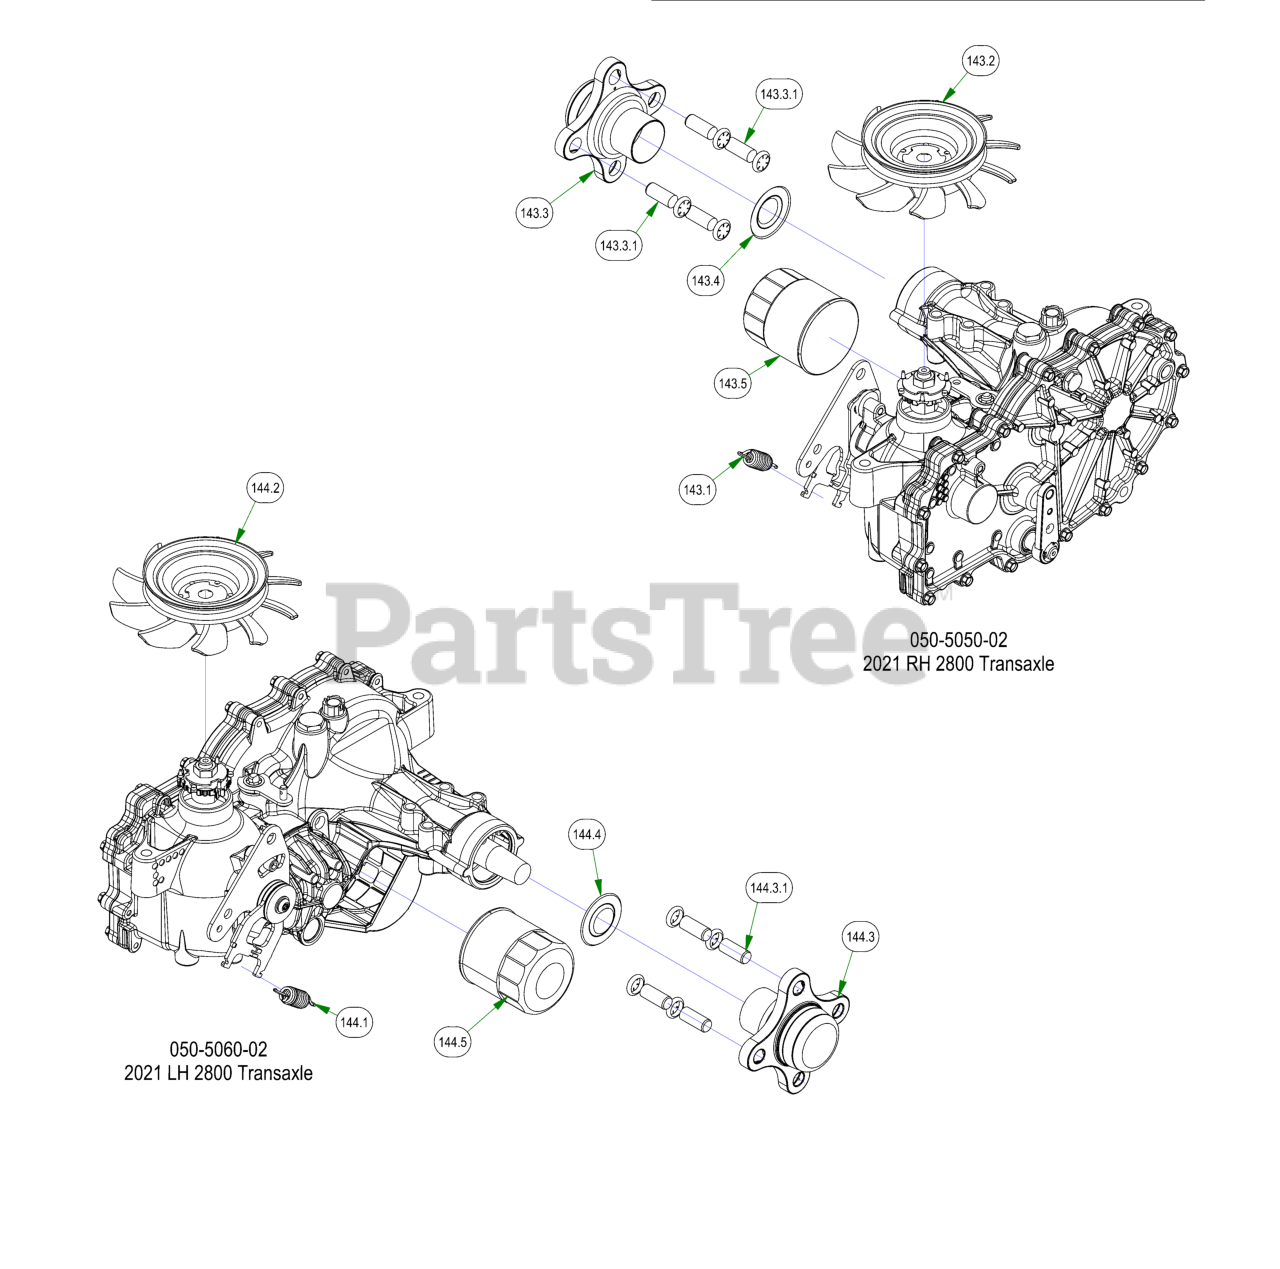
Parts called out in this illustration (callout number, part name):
83	1/4 USS FLAT WASHER (3/4 OD) ZINC
91	ZT Tire and Rim Assembly 22 x 11 - 10
143	2021 RH 2800 Transaxle
143.1	Gold Transaxle Spring
143.2	2021 ZT/Maverick Transaxle Fan/Pulley Kit
143.3	ZT Transaxle Wheel Hub
143.3.1	Transaxle Wheel Studs/ Drum Brake Studs
143.4	2021 ZT/Maverick Transaxle Seat Kit (ZT-2800)
143.5	ZT Hydraulic Filter
144	2021 LH 2800 Transaxle
144.1	Gold Transaxle Spring
144.2	2021 ZT/Maverick Transaxle Fan/Pulley Kit
144.3	ZT Transaxle Wheel Hub
144.3.1	Transaxle Wheel Studs/ Drum Brake Studs
144.4	2021 ZT/Maverick Transaxle Seal Kit (ZT-2800)
144.5	ZT Hydraulic Filter
